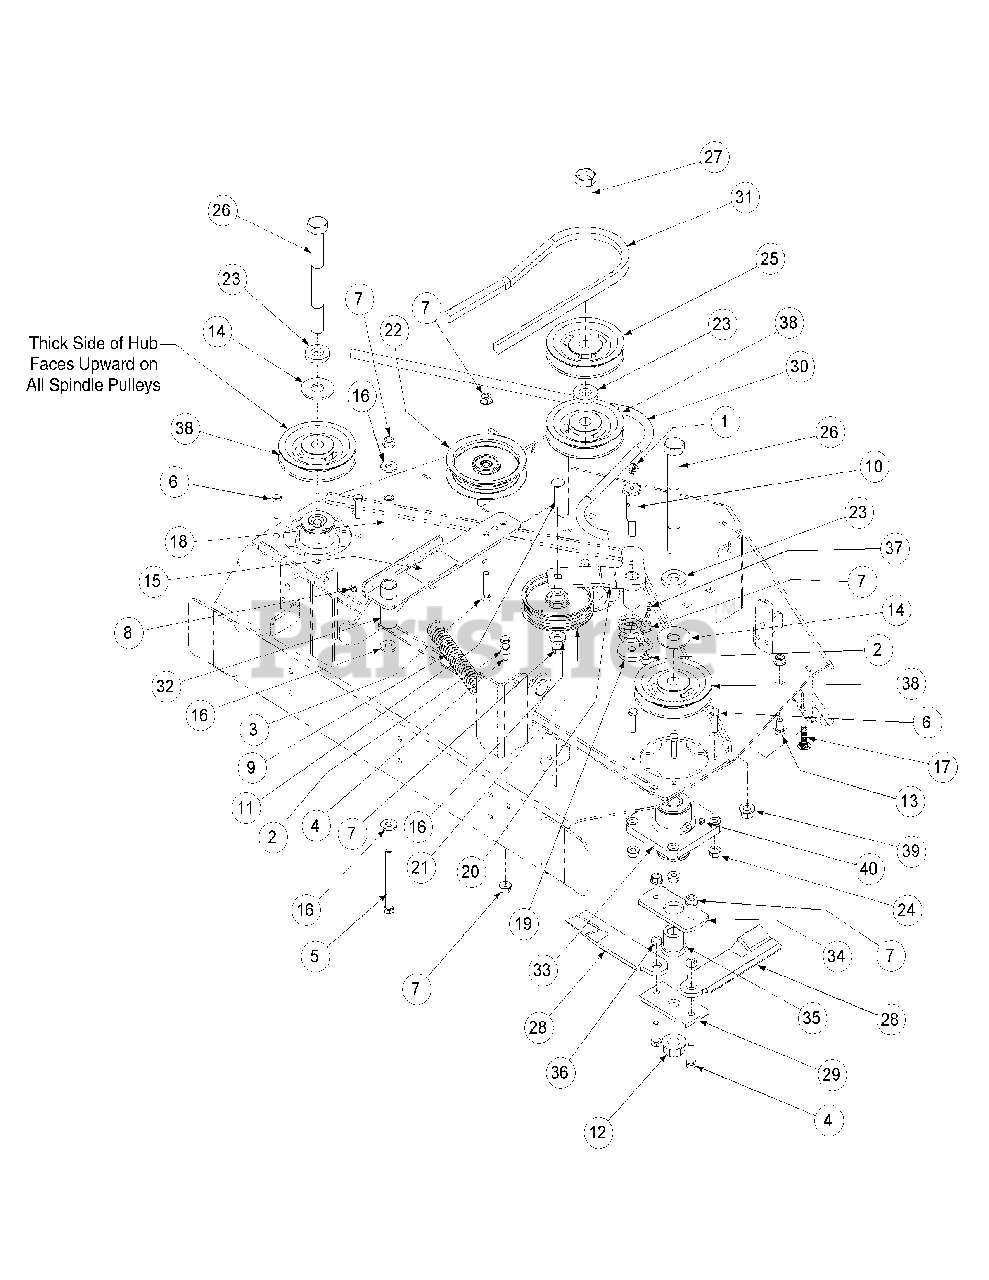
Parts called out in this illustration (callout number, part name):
1	Grease Fitting, 1/4-28 90 Deg.
2	Hex Nut 3/8-16
3	Hex Cap Screw, 3/8-16 x 1-1/2
4	Hex Cap Screw, 3/8-16 x 1-1/4
5	Hex Cap Screw, 3/8-16, 3.75
6	Hex Cap Screw, 5/16-18 x 1-1/4
7	Hex Nut, 3/8-16, Lock Flange
8	Grease Fitting, 1/4-28 x 3/16
9	Spring Extension, 1.0 OD x 5.125
10	Shoulder Screw, 7/16-14
11	Hex Carriage Screw, 3/8-16, 1.75
12	Hex Flange Nut, 3/4-16
13	Carriage Bolt, 3/8-16 x .75
14	Flat Washer, .781 ID, 2.00 OD, .105
15	Decal, Idler Location
16	Flat Washer, .406 ID, 1.0 OD, .105
17	Carriage Screw, 3/8-16 x 1.25
18	Spacer, .39 ID x .625 OD x 2.75
19	Flat Washer, 7/16 ID x 1.75 OD x .25
20	Idler Arm Assembly, Deck Spindle
21	Flat Pulley with Flanges
22	Idler Pulley, 4.06 OD w/Deep Flange
23	Flat Washer, .760 ID x 1.50 OD x .25
24	Hex Nut, 5/16-18, Lock Flange
25	V-Pulley, 4.75 OD
26	Hex Cap Screw, 3/4-16, 7.00
27	Hex Cap Screw, 3/4-16, 7.50
28	Blade, Short Fold
29	Blade Center Connector
30	V-Belt, A-Section
31	V-Belt, B-Section
32	Idler Arm Weldment
33	Spindle Assembly
34	Blade Upper Mount Plate
35	Blade Spacer
36	Spacer, .385 ID x .625 OD x .25
37	Idler Torsion Spring
38	V-Pulley, 4.60 OD (use with ref 23)
38	V-Pulley, 4.75 OD
39	Nut, 7/16-20, FlangeLock
40	Grease Fitting
